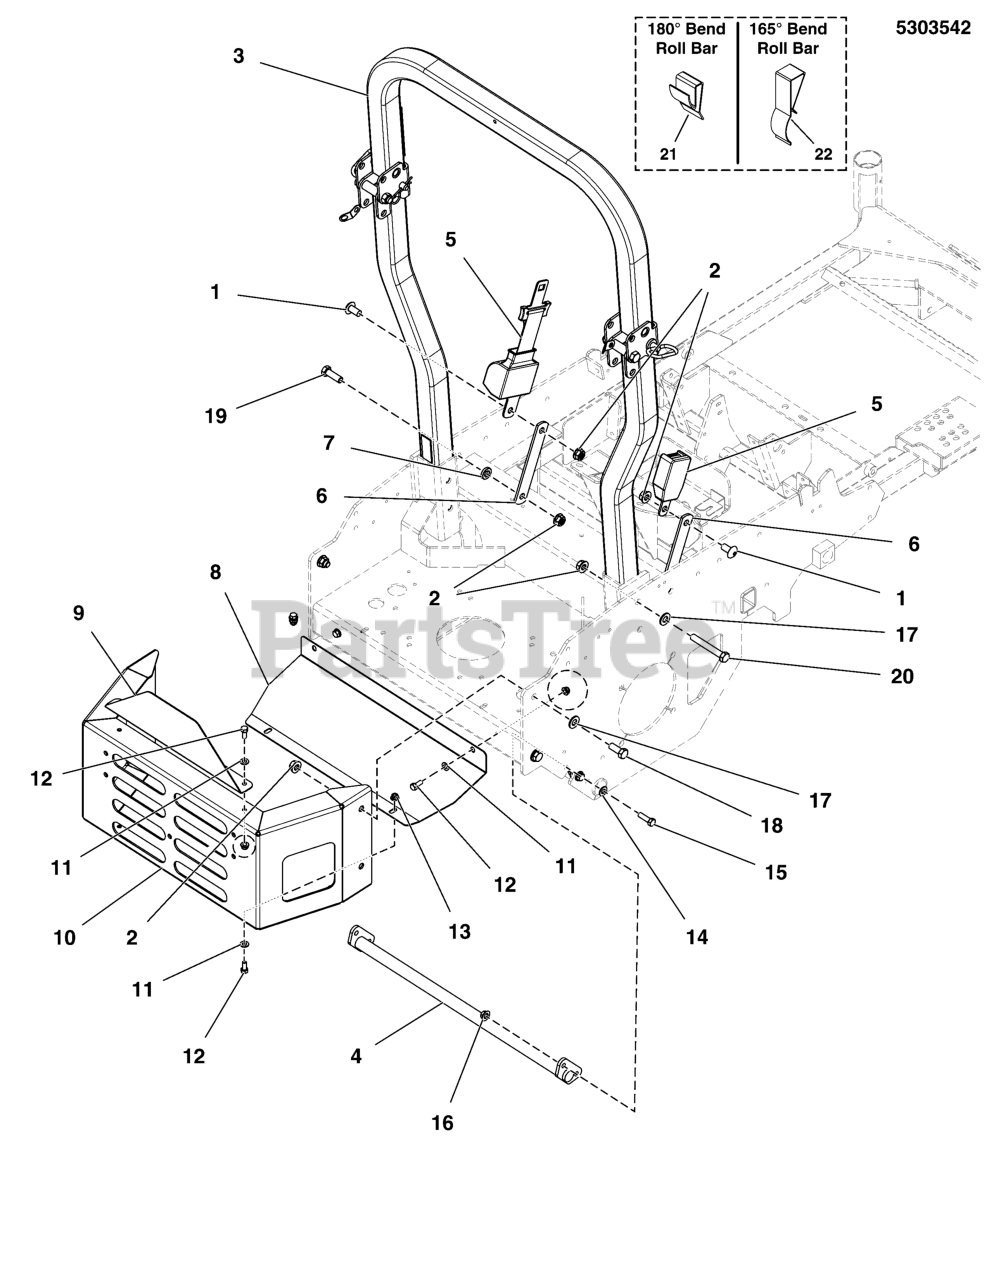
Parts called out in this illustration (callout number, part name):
1	SCREW, 1/2-13 X 1.00, SHCS
2	NUT, Hex Flange, Nylock, 1/2-13
3	ROPS (CALL 1-800-933-6175 X 207 FOR SERVICE)
4	WELD, BUMPER, REAR BRAKE - RED
5	SEAT BELT, RETRACTING - ASSM
6	BAR, MOUNT, SEAT BELT, IS700Z - BLK
7	SPACER, .52 X 1.00 X .22, PM, CZ
8	PLATE, HEAT SHIELD, S150XT - BLK
9	PLATE, CARB PROTECTOR - RED
10	WELD, BUMPER, S150XT - RED
11	WASHER, 5/16" SAE
12	BOLT, 5/16-18 X 3/4 GD5
13	NUT, 5/16-18 HEX NYLOCK FLANGE
14	WASHER, 3/8 SAE
15	BOLT, 3/8-16 X 1-1/4" GD5 CZ
16	NUT, 3/8-16 HEX SERRATED FLANGE
17	WASHER, 1/2 SAE
18	BOLT, 1/2-13 X 1-1/4 GD5 CZ
19	BOLT, 1/2-13 X 1-1/2 GD5 CZ
20	BOLT, 1/2-13 X 3-1/2, HEX HD, GD5, CZ (SV)
21	ANTI-RATTLE SPRING, FEMCO #230328972 (SV)
22	ANTI-RATTLE SPRING, ROPS, 165 DEGREE (SV)
